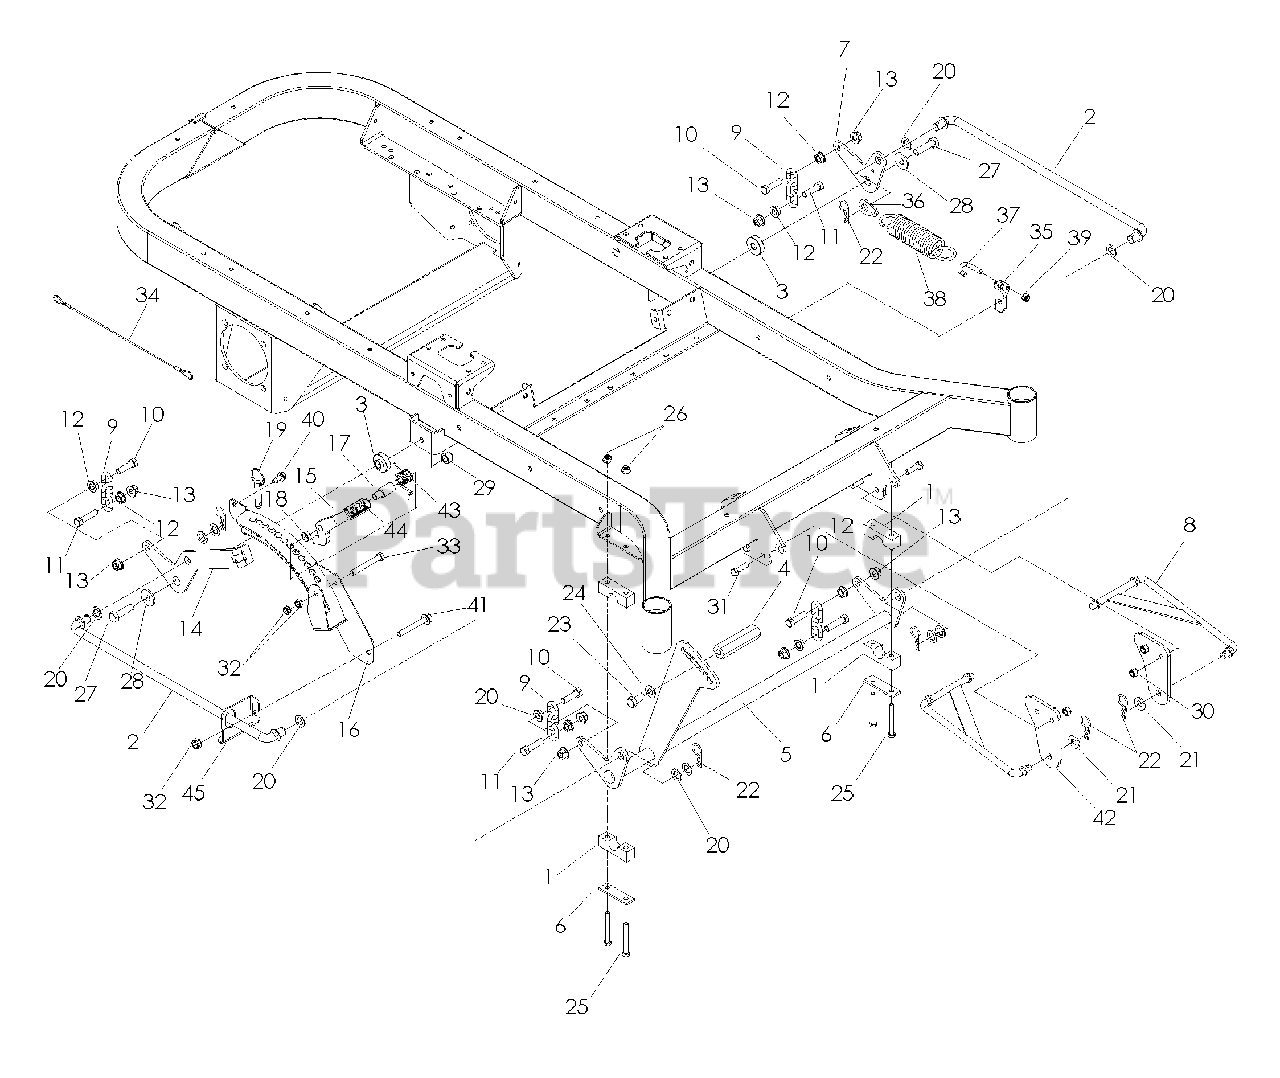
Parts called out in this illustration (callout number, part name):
1	PILLOW BLOCK
2	DECK LIFT LINK
3	IDLER SPACER
4	PEDAL, FOOT, HEX
5	SHAFT, FRONT-LIFT
6	REINFORCEMENT BAR
7	BELLCRANK, RR, LIFT
8	STRUT LINKAGE
9	LIFT CHAIN-3 LINK
10	HCS 7/16-14 x 1 1/2
11	HCS 7/16-14 x 1 3/4
12	NUT 7/16-14 HEX WHIZ LK
13	NUT 7/16-14 HEX WHIZ LK
14	BELLCRANK, RR, RT
15	LATCH, TRANSPORT
16	HEIGHT, ADJUST, DECK
17	PIVOT, LATCH, TRANSPORT
18	SPACER, .3
19	PIN, 1/2 x 1 1/2, DETENT RING
20	BUSHING .625
21	WASHER, SAE
22	PIN, COTTER 1 3/4
23	HCS 1/2-13 x 1 3/4
24	WASHER, 7/16" SPRING
25	HCS 5/16-18 x 2 3/4
26	NUT 5/16-18 FLANGE NYLOC
27	HCS 1/2-13 x 1 3/4 GR 8
28	WASHER 1/2 FLAT
29	NUT 1/2 HEX NYLOC
30	NUT 3/8-16 HEX NYLOC
31	HCS 3/8-16 x 1 1/4
32	NUT 3/8-16 HEX JAM NYLOC
33	HCS 3/8-16 x 3
35	MOUNT, SPRING
36	TAB, SPRING
38	SPRING, DECK BELTS
39	NUT 5/16-18 NYLOC
40	BOLT 5/16-18 x 3/4 THD FRM
41	HHFS 3/8-16 x 2 3/4
42	MOUNT, STRUT 52", 61"
42	MOUNT, STRUT, 72"
43	SPRING, TORSION
45	SUPPORT, LIFT LINKAGE MZ7227 ONLY
